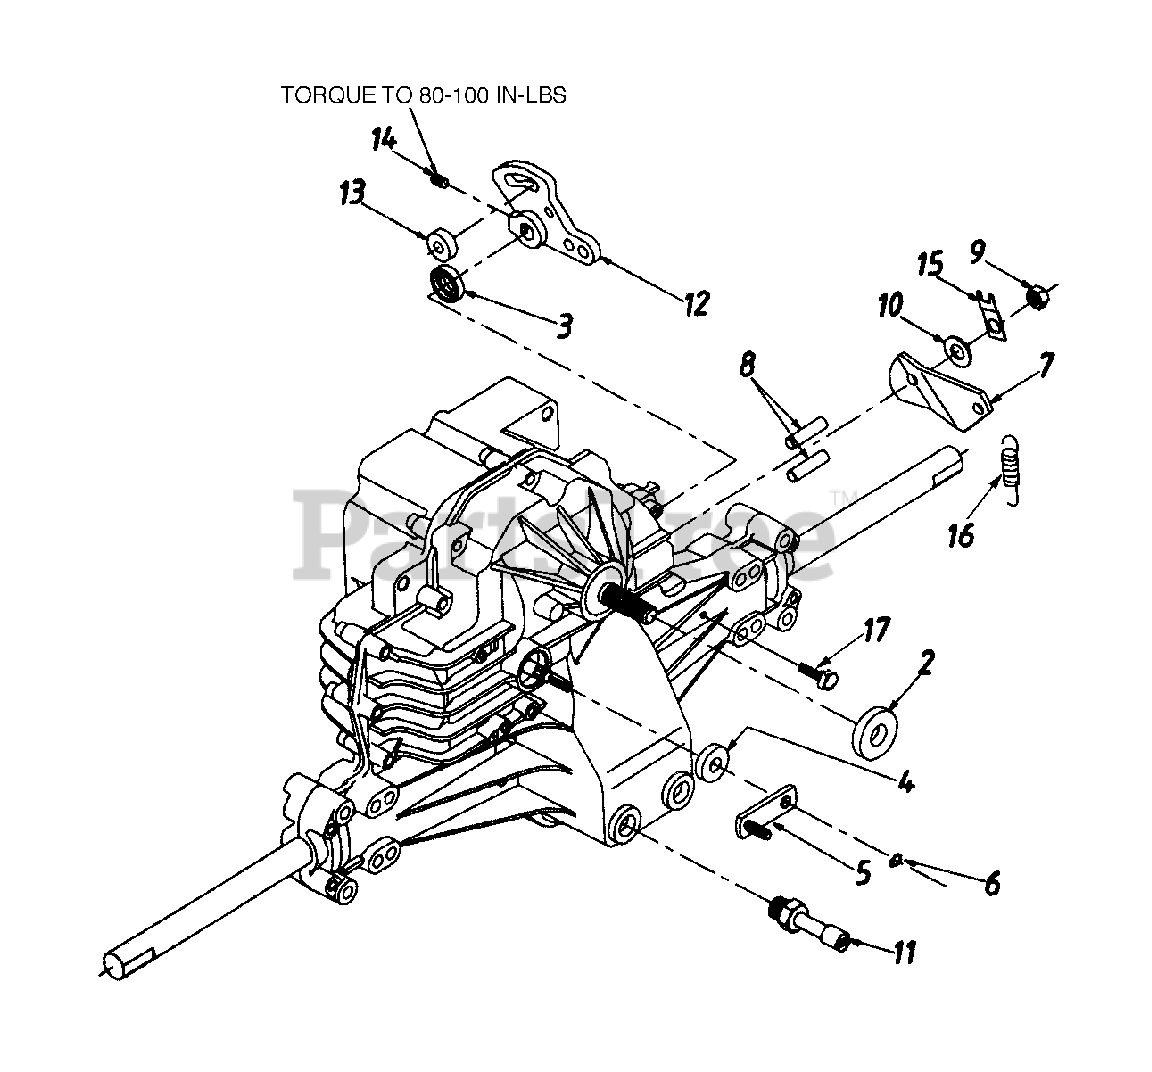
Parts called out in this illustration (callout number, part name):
4	Seal - Lip 10 x 25 x 7
5	Arm - Bypass
6	Ring - Retaining
7	Arm - Actuating
8	Pin - Actuating
9	Nut - Hex Lock 5/16-24 UNJC
10	Washer 7/16" x 7/8" x .060"
11	Breather Ass'y.
12	Arm - Control
13	Puck - Dampener
14	Set Screw
15	Strap, Locking
16	Spring, Extension
17	Self Tapping Screw #10-32 x .5"
